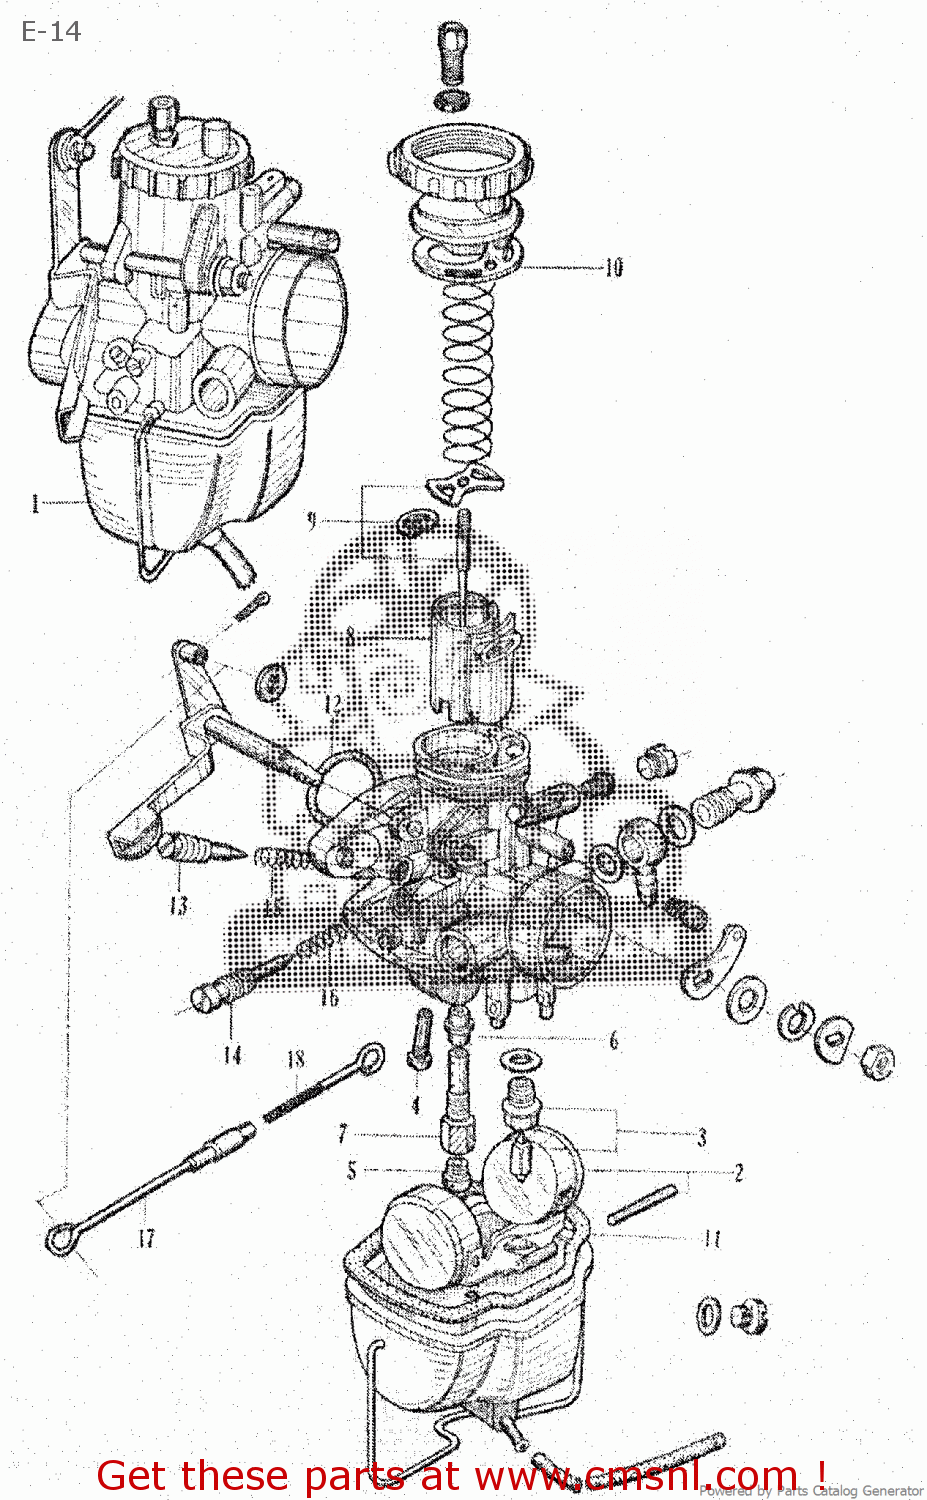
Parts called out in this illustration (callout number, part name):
1	CARBURETOR ASSY, LEFT
2	FLOAT
3	VALVE SET, FLOAT
4	JET SLOW SIZE 40
5	JET MAIN SIZE 115
6	JET NEEDLE
7	HOLDER NEEDLE
8	CARBURETOR ASSY, LEFT
9	NEEDLE JET
10	WASHER TOP
11	WASHER CHAMBER
12	O RING
13	SCREW AIR
14	SCREW THROTTLE
15	SPRING AIR SCREW
16	SPRING THROTTLE
17	ROD A VALVE
18	ROD B VALVE
